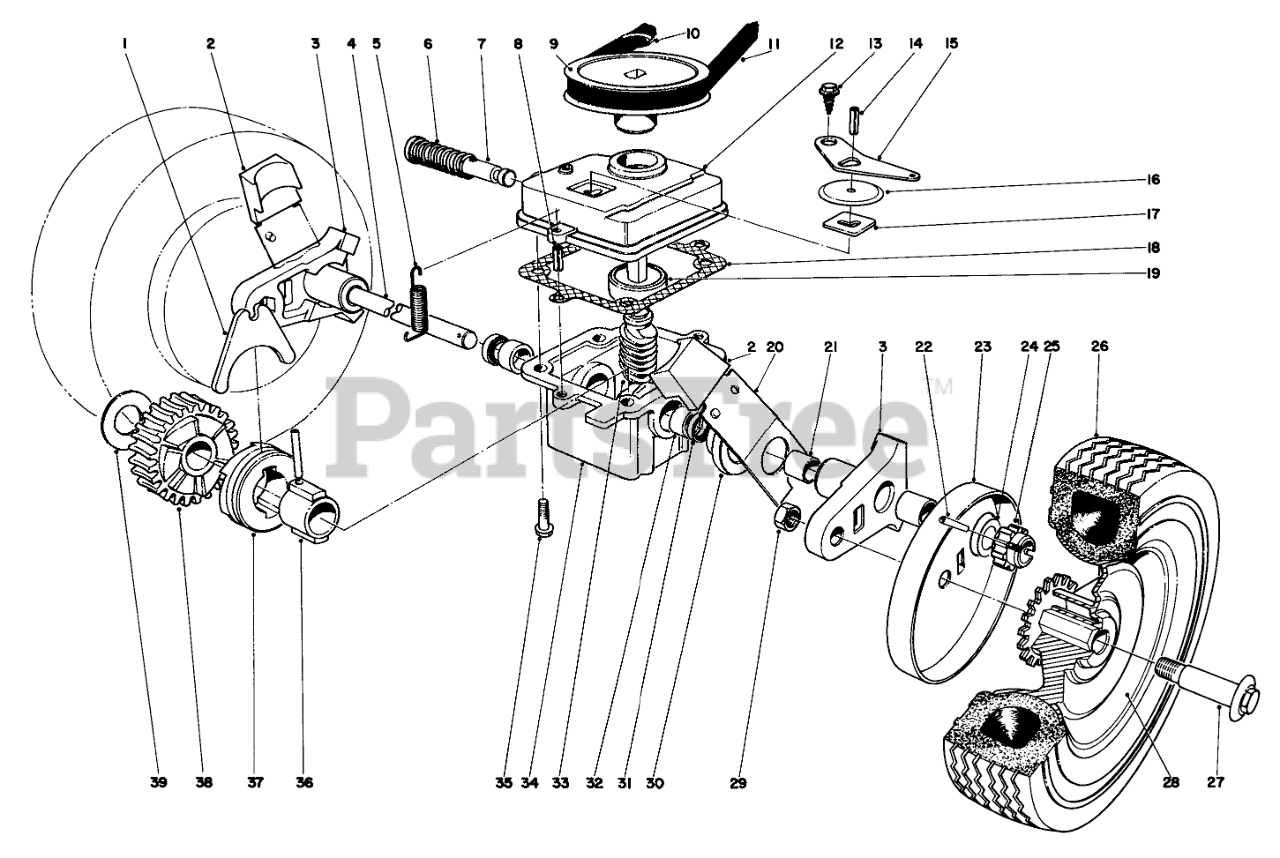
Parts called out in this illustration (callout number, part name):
1	SHIFTER FORK
2	Knob
3	Pivot Arm (Incl. Ref. No. 21)
4	Drive Shaft
5	TENSION SPRING
6	SPRING
7	Shift Rod
8	3/16 X 1/2 ROLL PIN
9	PULLEY
10	PUSH-ON 93-3236
11	V-Belt
12	GEAR CASE COVER
13	Screw
14	PIN-ROLL
15	SHIFTER ARM
16	TRANS DUST COVER
17	LATCH PLATE
18	GASKET
19	Ball Bearing
20	LH SPRING ARM ASM
21	BUSHING
22	COIL PIN
23	WHEEL COVER
24	WASHER-THRUST
25	Pinion
26	8 TIRE
28	Bushing
29	Nut
30	End Cap
31	Seal
32	Bushing
33	WORM SHAFT
34	Gear Case (Incl. Ref. No. 32)
35	Screw
36	SLEEVE
37	CLUTCH JAW
39	THRUST WASHER
